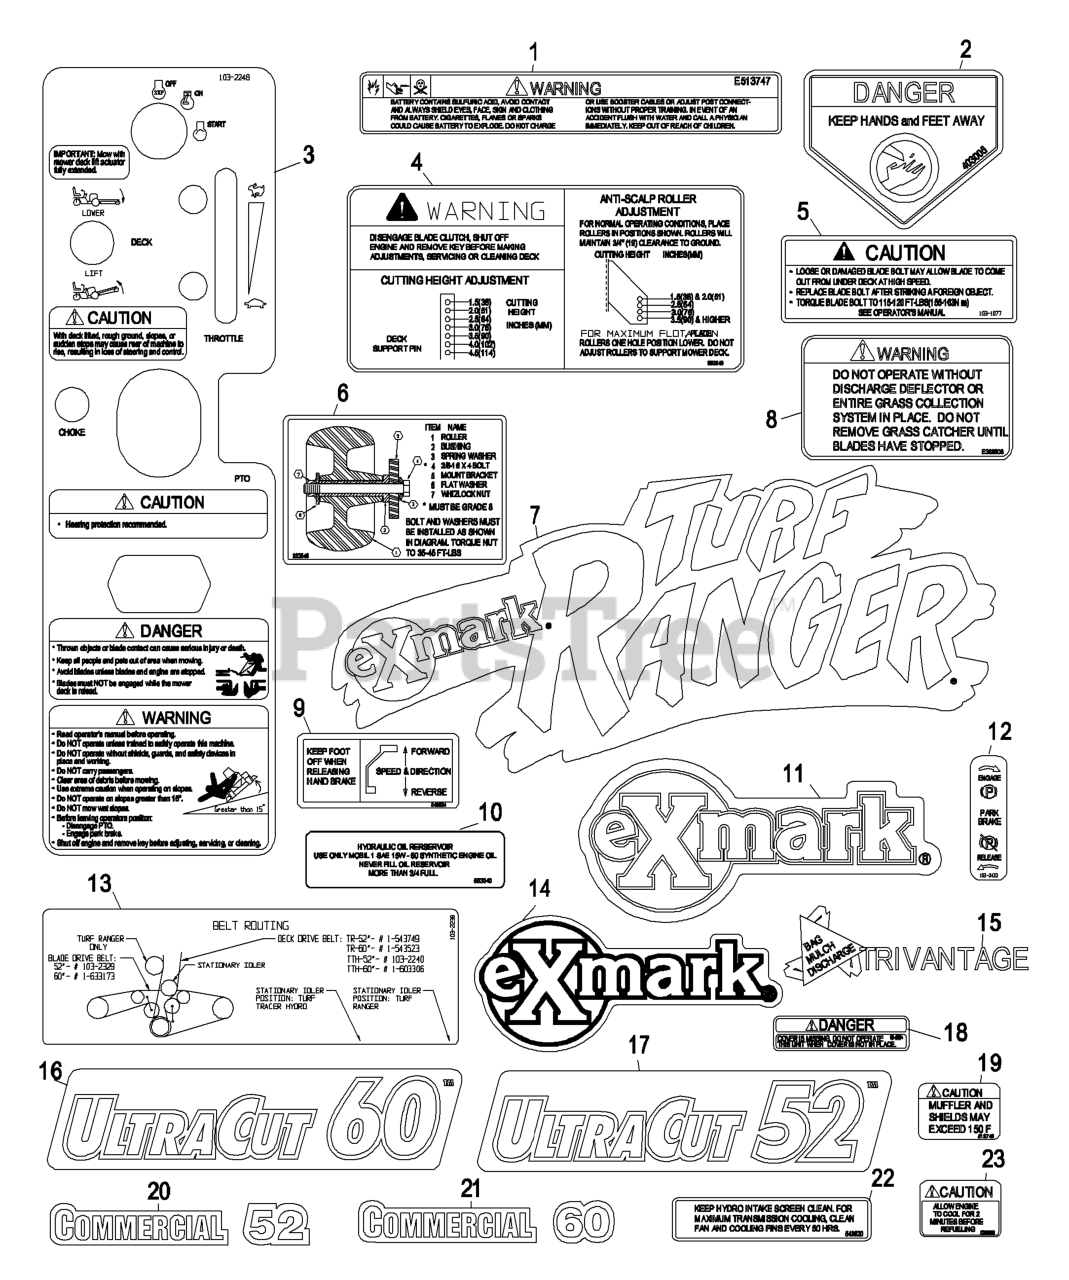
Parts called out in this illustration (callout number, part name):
1	DECAL-BATTERY
2	DECAL-DANGER
3	DECAL, CONSOLE
4	DECAL,ANTI SCALP
5	DECAL,BOLT TORQUE
6	DECAL,ROLLER MOUNTING
8	DECAL-WARNING, DISCHARGE
9	DECAL,FOOT PEDAL
10	DECAL,HYDRAULIC TANK
12	DECAL,PARKING BRAKE
13	DECAL,BELT ROUTING
14	DECAL,EXMARK LOGO
16	DECAL,ULTRACUT 60
17	DECAL,ULTRACUT 52
18	DECAL-COVER, MISSING
20	DECAL,COMMERCIAL 52
21	DECAL,COMMERCIAL 60
22	DECAL,INTAKE
